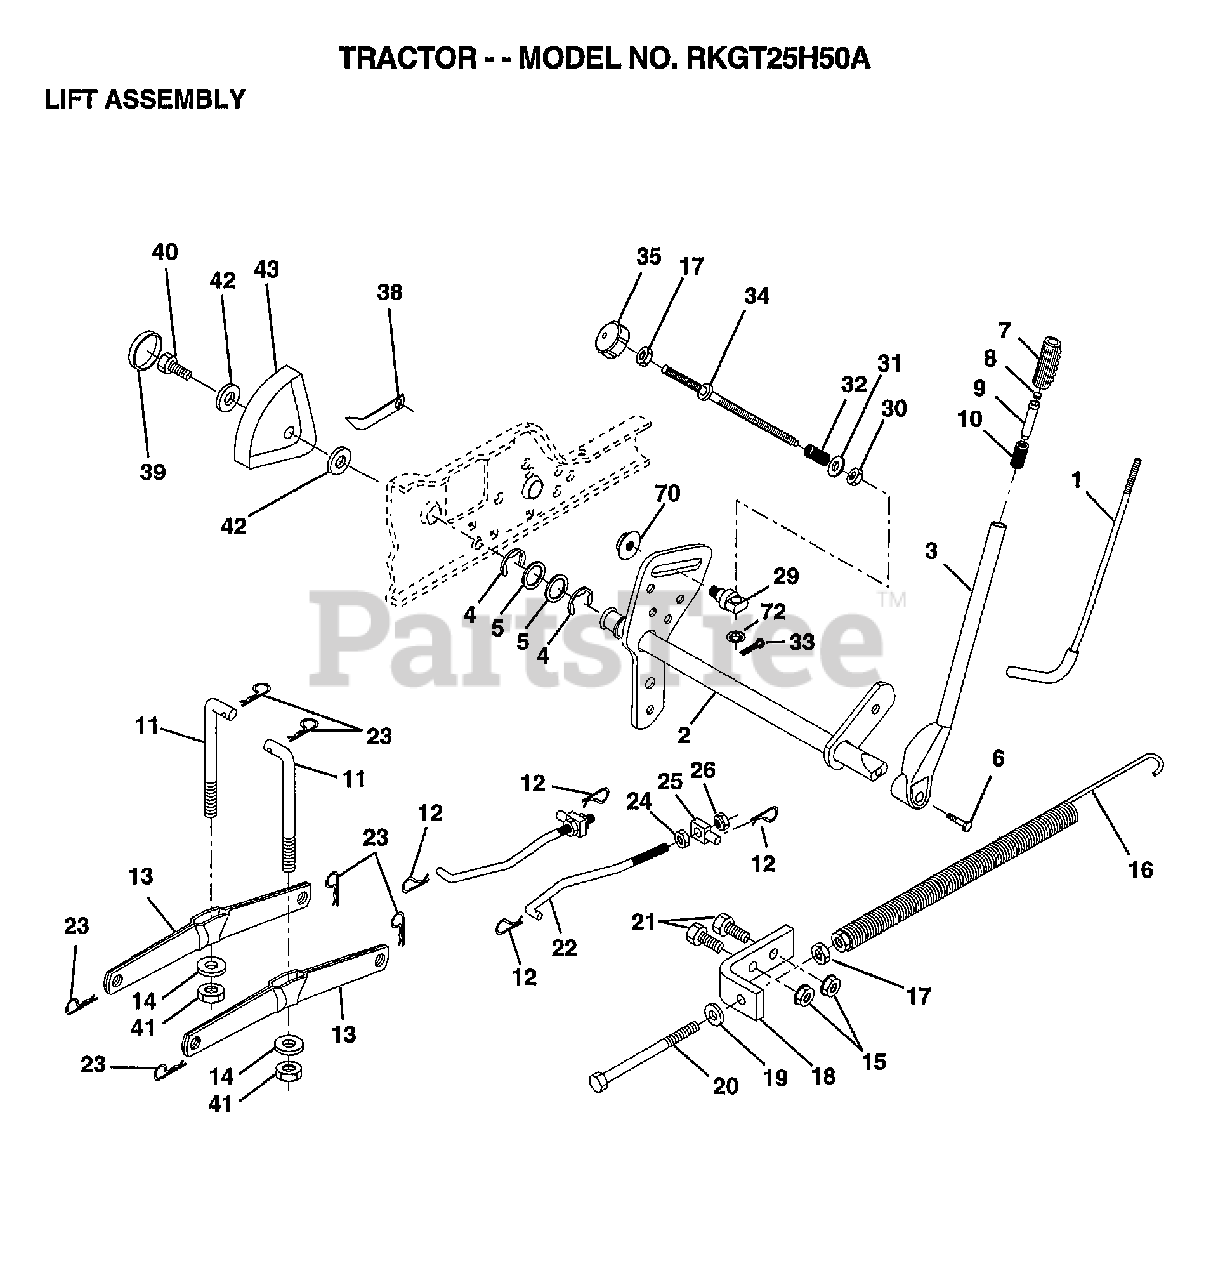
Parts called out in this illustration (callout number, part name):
1	LEVER ROD LT
2	SHAFT.ASM.LIFT.VGT
3	LEVER.ASM.LIFT.RH
4	E-RING
5	WASHER
6	"BOLT,HEX"
7	GRIP, HANDLE
10	SPRING T
11	LINK.LIFT.MWR.VGT
12	RETAINER SPRING
13	ARM SUSP REAR
14	BEARING PVT LH
17	NUT
18	BRACKET SPRING AS
19	WASHER
20	BOLT-ADJ SPRING T
21	BOLT
22	LINK.FRONT
24	NUT
25	TRUNION
26	NUT.LK.W/WSH.1/2.
29	TRUNNION
30	NUT T
31	WASHER
32	SPRING.COMP.INF.H
34	ROD.ADJ.LIFT
35	KNOB INF 3/8-16
38	POINTER HEIGHT INDICATOR
39	"PLUG,HOLE"
40	SCREW
41	NUT.CROWNLOCK.3/8
42	WASHER
43	HEIGHT INDICATOR
70	NUT.HXFLG.LOCK.
72	NUT PUSH M
